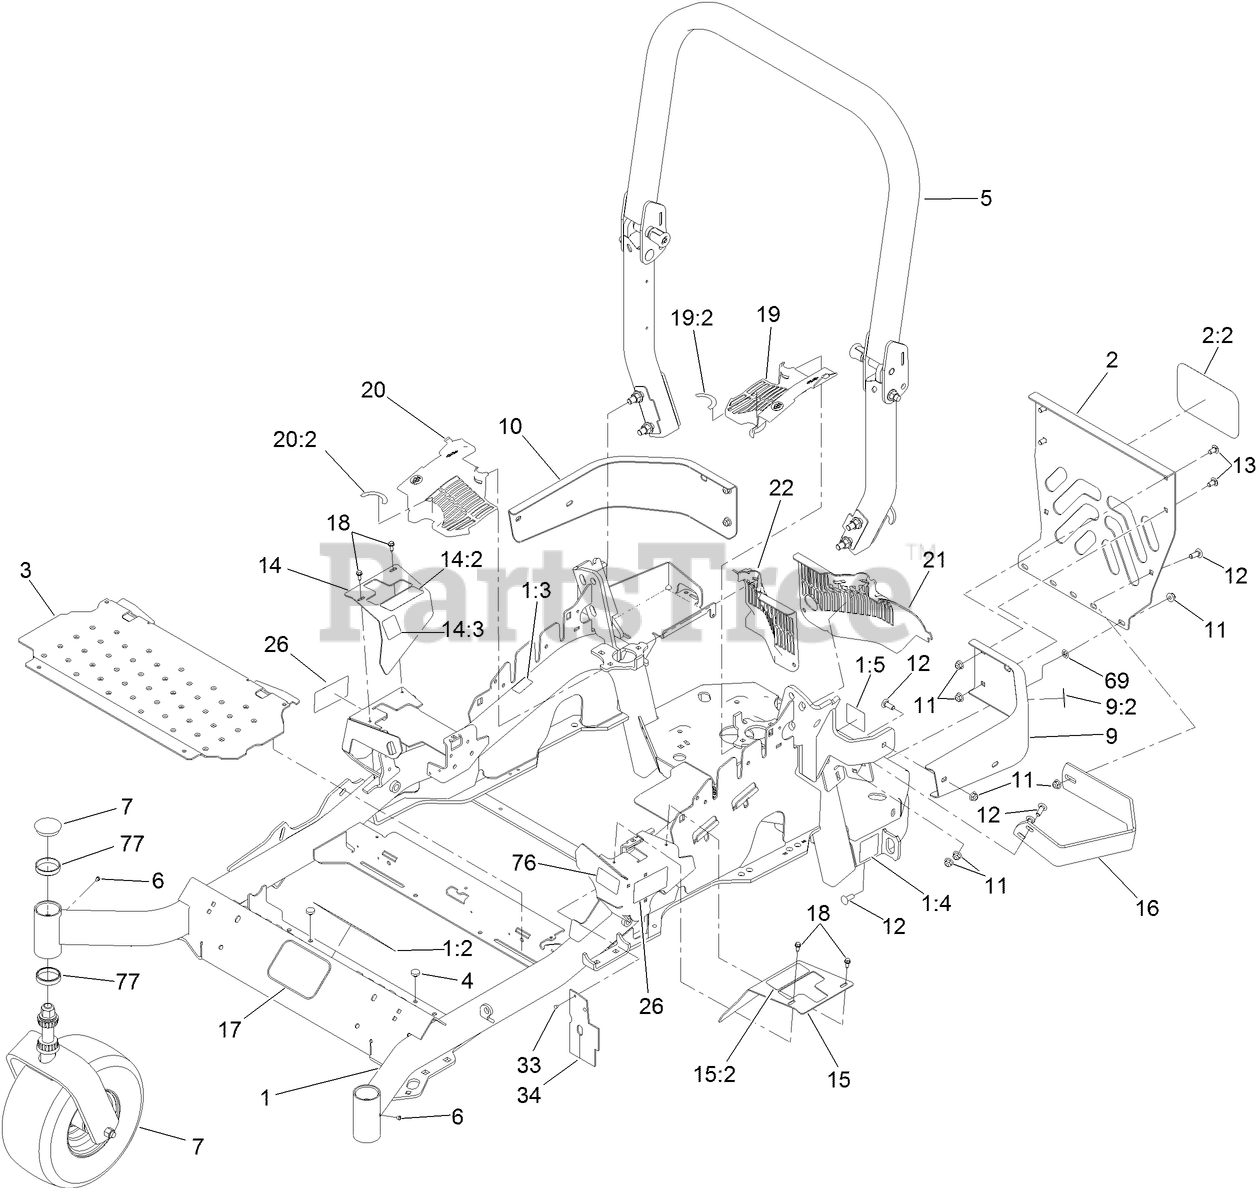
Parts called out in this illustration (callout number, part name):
1	MAINFRAME ASM
1:2	DECAL-WARNING
1:3	DECAL-WARNING, SLOPE
1:4	DECAL-HAZARD, PINCHED FINGER
1:5	DECAL-SPARK ARRESTER
2	REAR GUARD ASM
2:2	DECAL
3	FLOORPAN
4	BUMPER
5	ROPS ASM
7	Caster Wheel ASM
9	LH BUMPER ASM
9:2	DECAL-WARNING
10	BUMPER-RH
11	NUT-HF, NI
12	SCREW-CARR
13	SCREW-CARR
14	RH MOTION CONTROL COVER ASM
14:2	DECAL-CONTROL, MOTION
14:3	DECAL-PARK BRAKE, CE
15	LH MOTION CONTROL COVER ASM
15:2	DECAL-CONTROL, MOTION
16	GUARD-MUFFLER
17	DECAL
18	SCREW-HWH
19	LH HYDRO GUARD ASM
19:2	DECAL-OIL, HYDRO
20	RH HYDRO GUARD ASM
20:2	DECAL-OIL, HYDRO
21	GUARD-HYDRO, REAR (LH)
22	GUARD-HYDRO, REAR (RH)
33	RIVET-POP
34	DEFLECTOR-AIR FLOW
69	NUT-PUSH
76	DECAL-FUEL FILL, CE
77	CUP-BEARING
